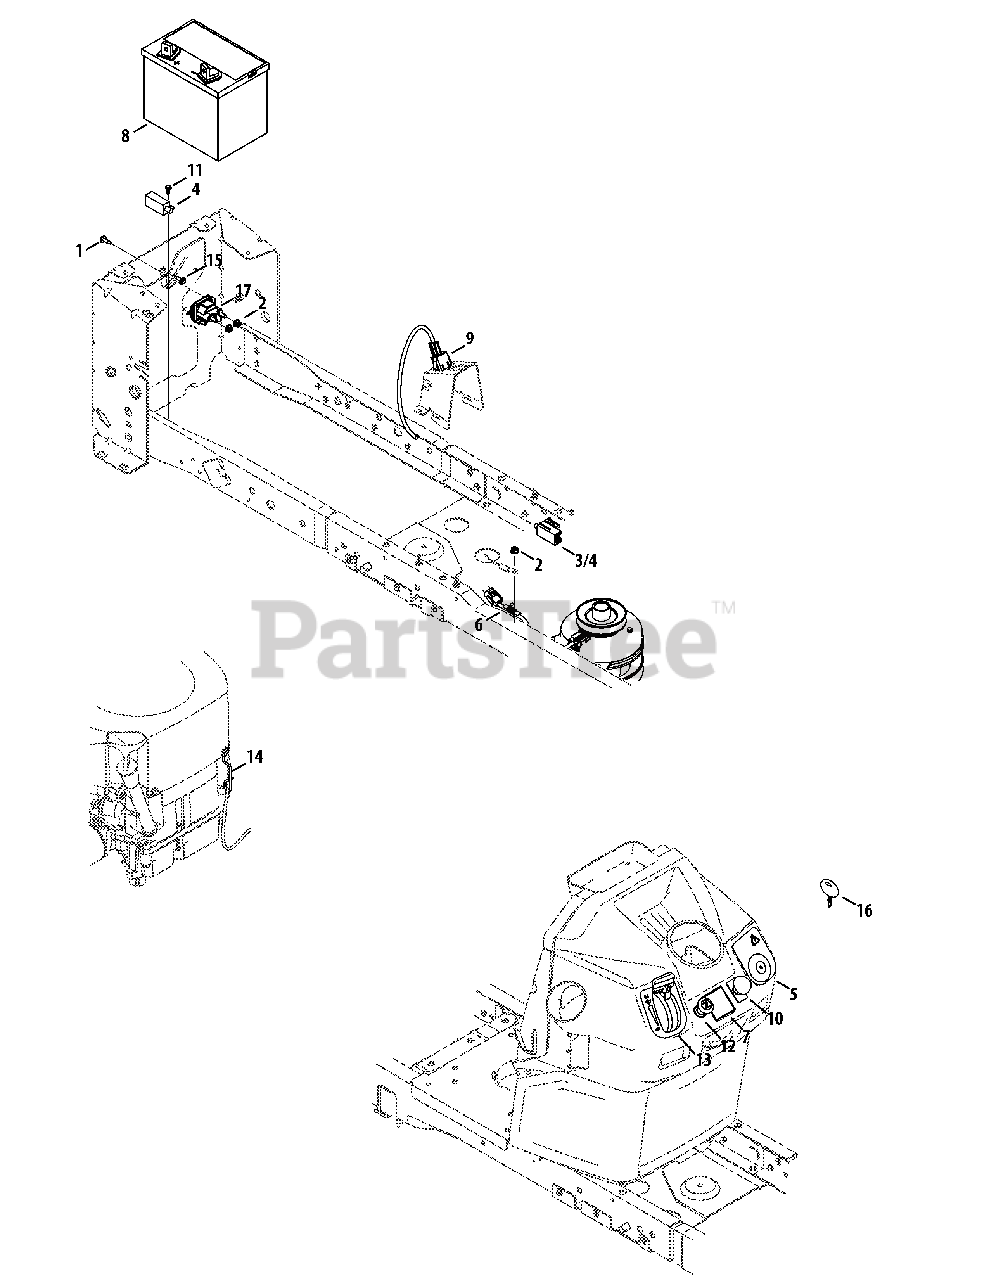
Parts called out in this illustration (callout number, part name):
1	Screw, M6-1 x .625
2	Nut, Jam Lock, 1/4-20, Nylon
3	Switch, 3-Pole (Man. PTO)
4	Switch, Interlock
5	Key Switch (Elec. PTO)
6	Jumper Harness (Elec. PTO)
7	Hour Meter
8	Battery
9	Dash Harness (Elec. PTO)
10	PTO Switch (Elec. PTO)
11	Shoulder Screw, #10-32 x .500
12	Choke Plug
13	Throt/Choke Cable, 43.5"
14	Cable Guide Rod
15	Self-tapping Screw, 1/4-20 x .625
17	Solenoid
